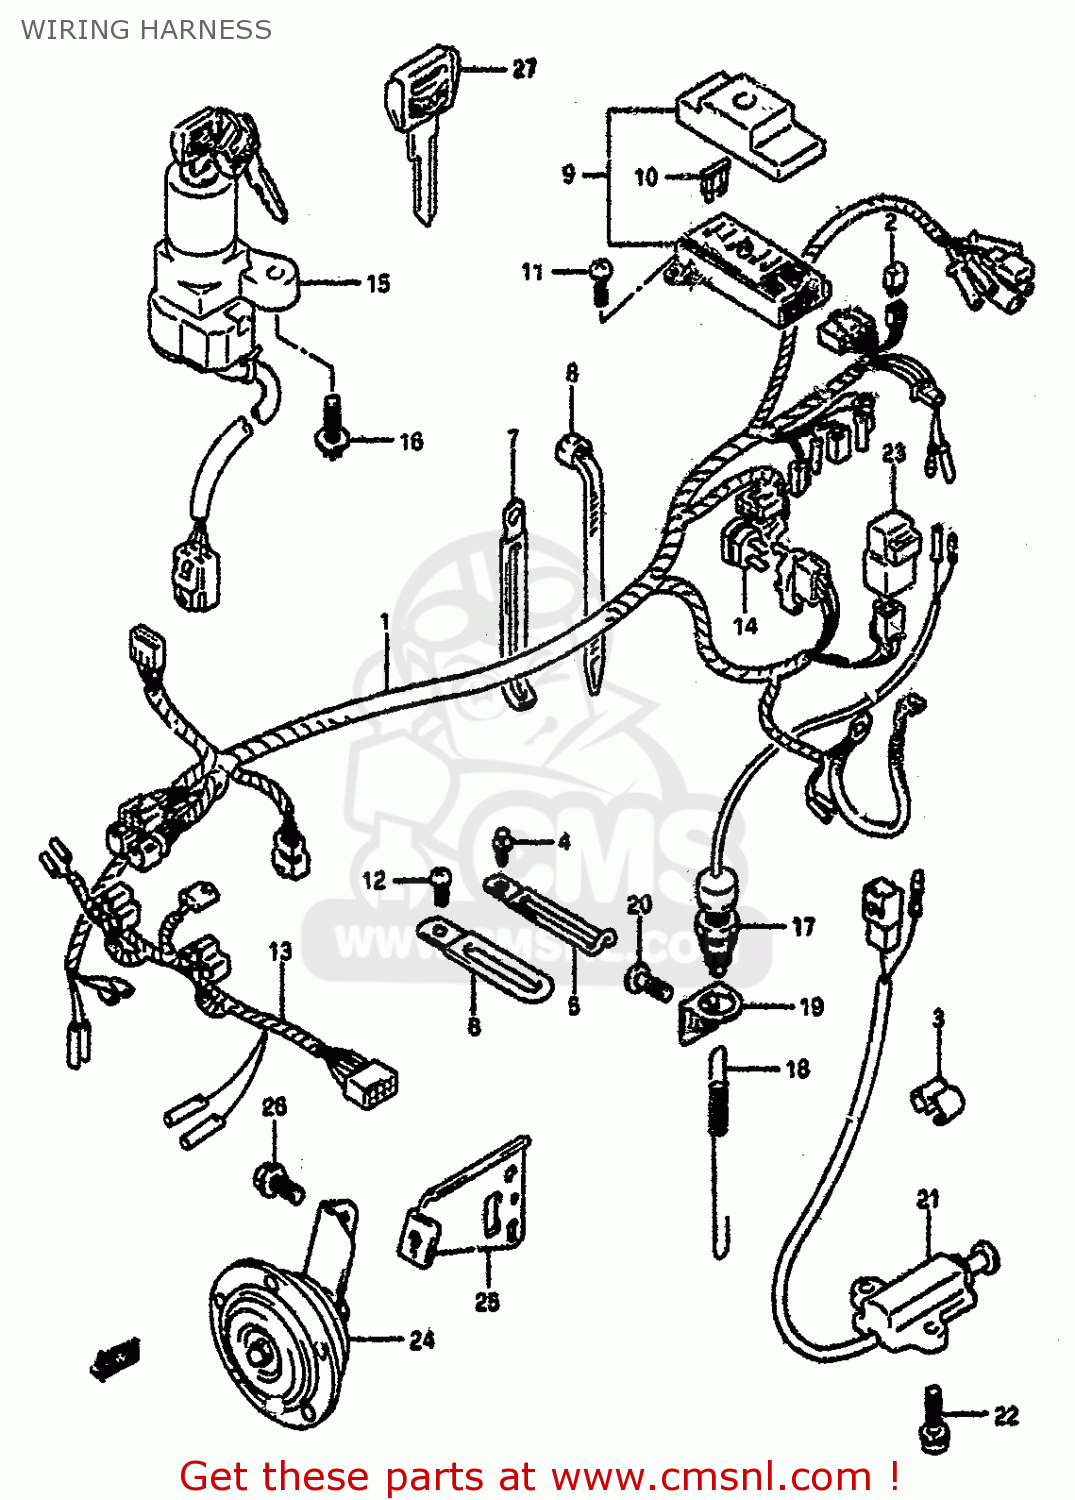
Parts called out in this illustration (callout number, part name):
1	HARNESS, WIRING
2	DIODE(STANLEY DE8804)
3	CLIP
4	CLIP
5	CLAMP
6	CLAMP
7	CLAMP
8	CLAMP(L:95)
9	BOX ASSY,FUSE
10	FUSE(10A)
11	SCREW
12	SCREW
13	WIRE, HEADLAMP LEAD
14	BREAKER ASSY,CIRCUT
15	LOCK ASSEMBLY,STEERING
16	SCREW(6X18)
17	SWITCH ASSY,STOP LAMP
18	SPRING
19	BRACKET,STOP LAMP SWITCH
20	SCREW(6X12)
21	SWITCH ASSEMBLY,SIDE STAND
22	SCREW
23	RELAY ASSEMBLY
24	HORN ASSEMBLY
25	BRACKET, HORN
26	BOLT
27	KEY,BLANK
